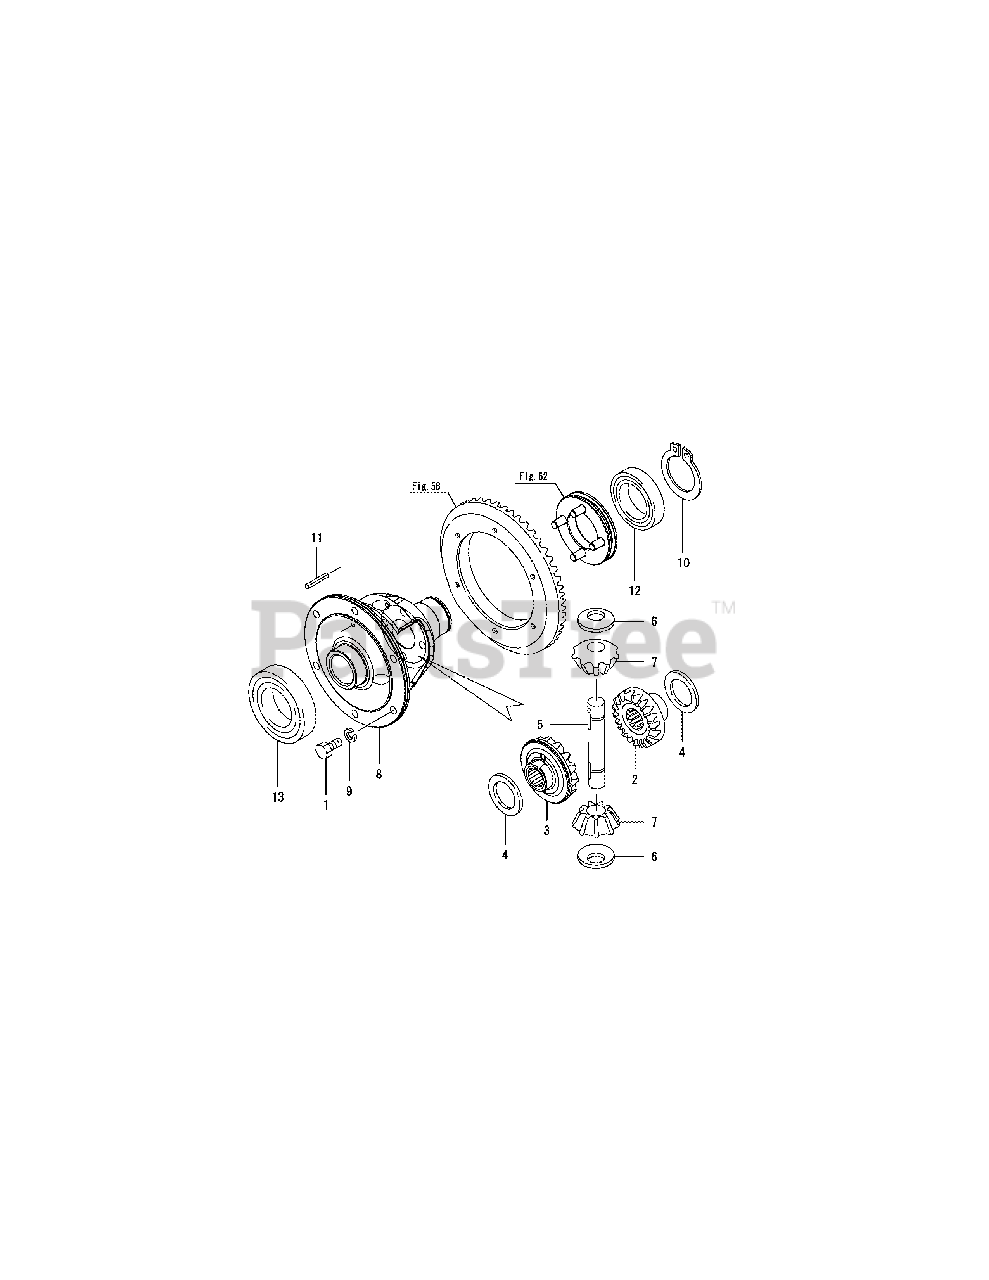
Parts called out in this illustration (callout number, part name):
2	GEAR, DIFFERENTIAL
3	GEAR, DIFFERENTIAL
4	WASHER, DIFFERENTAIL
5	SHAFT, DIFF. PINION
6	WASHER,DIFF PINION
7	PINION,DIFFERENTIAL
8	HOUSING, DIFF.
9	SPRING WASHER 10
11	SPRING PIN 6X36
